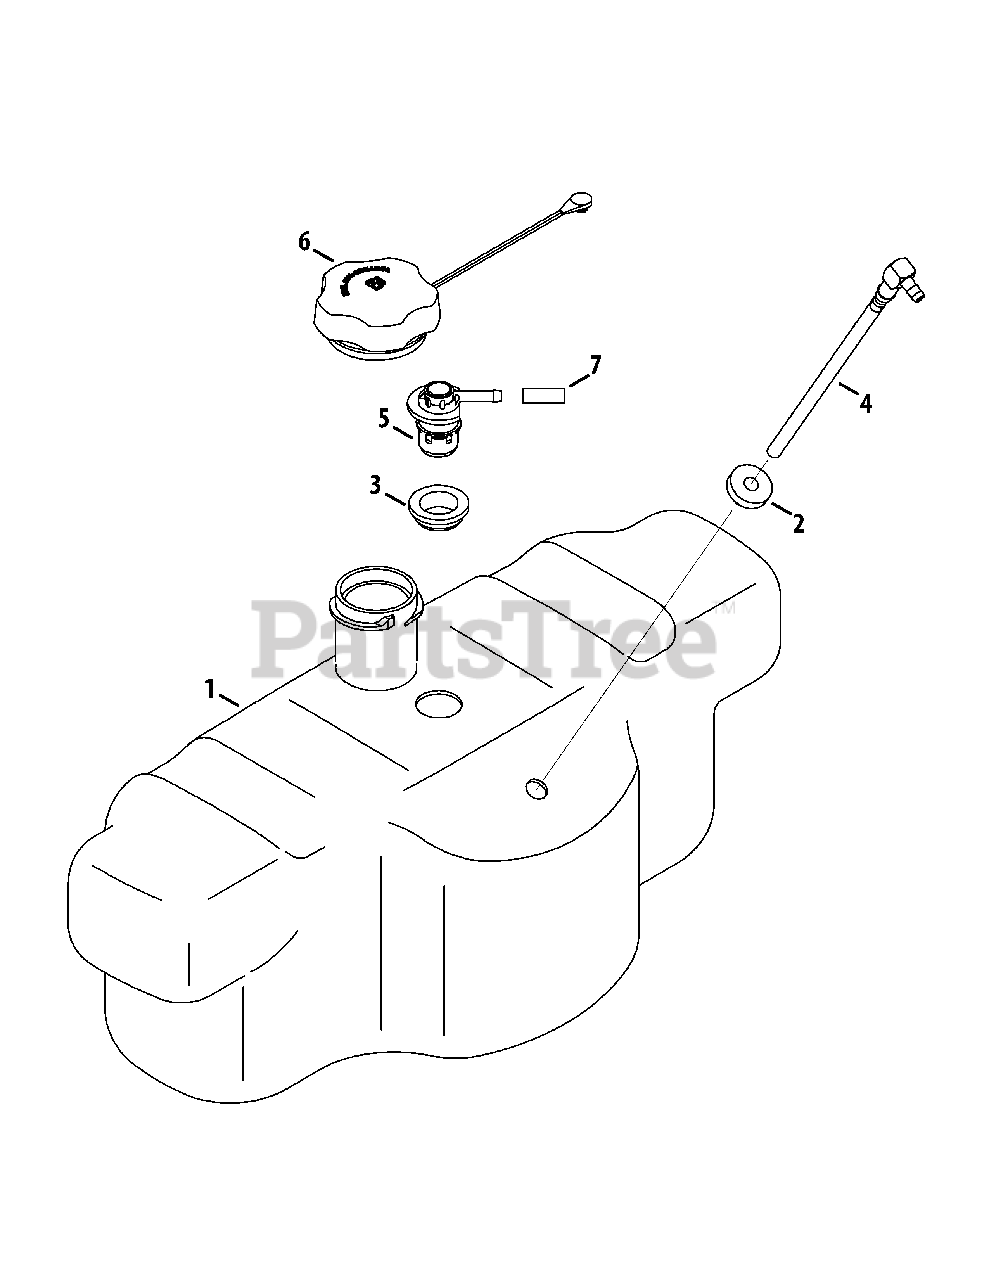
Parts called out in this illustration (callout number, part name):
1	Fuel Tank
2	Fuel Tank Bushing
3	Rubber Grommet
4	Fuel Pickup Fitting
5	Rollover Valve
6	Fuel Cap
7	Vent Hose
